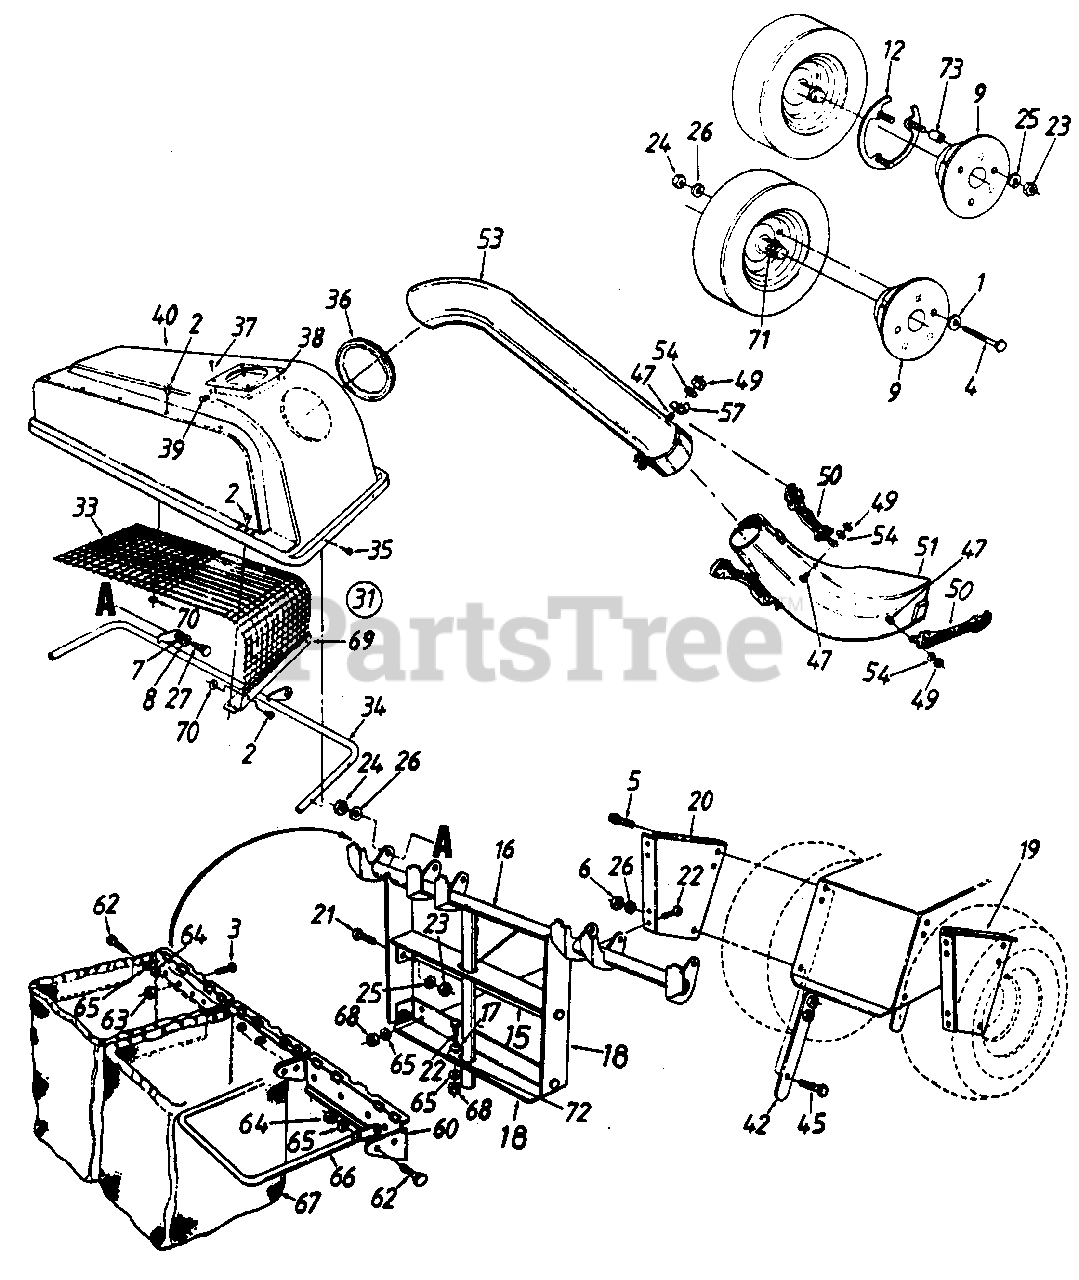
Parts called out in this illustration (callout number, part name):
1	Fl-Wash . . 385 " 1. D .
2	Pop Rivet
3	Truss Mach. Scr. #10-24 x . 38 " Lg .
4	Hex Bolt 3/8-16 x 4.5' Lg.
5	Hex Wash. Hd. Tap Scr. 5/16-18 x .62"
6	Hex Nut 3/8-24 Thd.
7	Bell-Wash. .515 I.D.
8	Fl-Wash . . 510 " I . D .
9	Wheel WWeights
12	Wheel Weight Snap Ring
15	Catcher Support Tube Mtg. Brkt.
18	Catcher Latch and Support Brkt.
22	Hex Bolt 1/4-20 x .62" Lg.-Grade 5
23	Hex Nut 5/16-18 Thd.
24	Hex Nut 3/8-16 Thd.
25	L-Wash. 5/16" I.D.
26	L-Wash. 3/8" I.D.
27	Shld. Bolt 3/8-16 x .500" Dia.
31	Grass Catcher Cover Ass'y. Comp.
33	Screen
36	Tube Seal
37	Truss Mach. B-Tap Scr. #10 x.5" Lg.
38	Plastic Platc
39	Speed Nut
40	Grass Catcher Cover
47	Hex Bolt 1/4-20 x .50" Lg.
49	Hex Ins. L-Nut 1/4-20 Thd.
50	Retainer Strap Ass'y.
51	Discharge Chute
53	Catcher Elbow Tube
54	L-Wash. .270" I.D. x .57" O.D.
57	Retainer Hook Brkt.
62	Hex Bolt 1/-28 x .75" Lg.
63	Hex Sems Nut #10-24 Thd.
64	Hex Nut 1/4-28 Thd.
65	L-Wash. 1/4" I.D.'
66	Catcher Bag Frame
67	Grass Catcher Bag
68	Hex Nut 1/4-20 Thd.
71	Foam Strip 1-1/8" x 1-1/2" x 3/8"
73	Spacer
